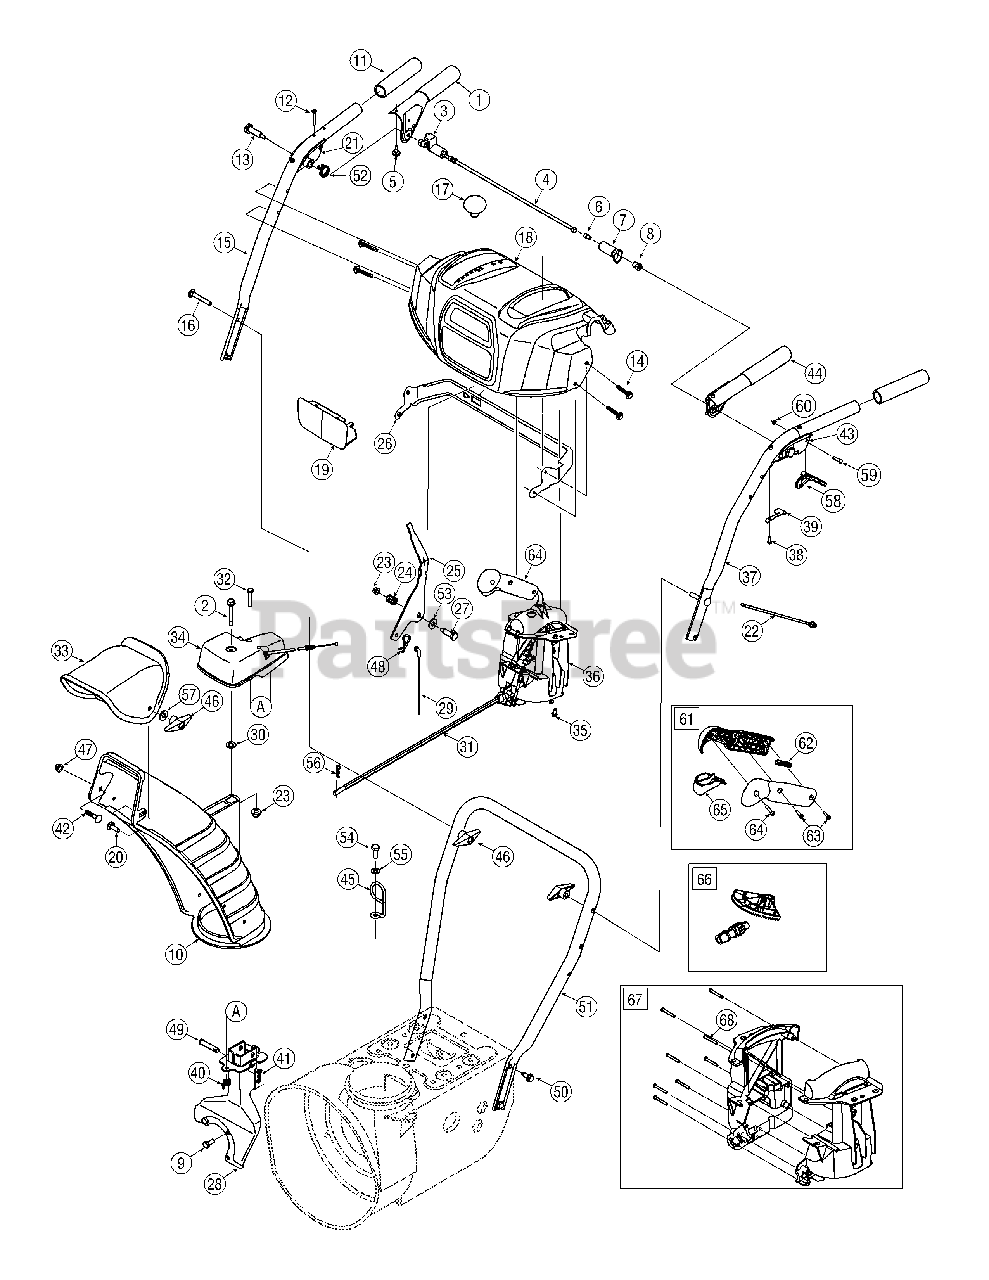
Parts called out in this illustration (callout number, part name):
1	Handle Engagement Assembly RH
2	Flange Shoulder Screw
3	Lock Plate
4	Pivot Rod
5	Rubber Bumper
6	Screw, 1/4-20 x .500
7	Clutch Lock Cam
8	Shoulder Nut, 1/4-20
9	Hex Screw, 5/16-24 x .750
10	Lower Chute
11	Handle Grip
12	Screw, #10-24 x 0.375
13	Shoulder Screw, 1/4-20
14	Screw, 1/4-20 x 1.625
15	Upper Handle RH
16	Carriage Screw, 5/16-18 x 2.25
17	Shift Knob
18	Handle Panel
20	Carriage Bolt, 5/16-18 x 1.0
21	Handle Clutch Lock RH Assembly
22	Cable Tie
23	Flange Lock Nut, 1/4-20
24	Compression Spring
25	Shift Lever
26	Panel Bracket
27	Shoulder Screw
28	Chute Support Bracket
29	Speed Selector Cable
30	Flat Washer, .25 x .630 x .0515
31	Chute Rod
32	Hex Screw, 1/4-20 x 3.00
33	Upper Chute
34	Gearbox Assembly
35	Hi-Lo Screw, 1/4-15 x 0.5
36	2-Way Chute Control Assembly
37	Upper Handle LH
38	Screw, #8-16 x 0.50
39	Clutch Lock Spring
40	Wing Nut, 1/4-20
41	Bow Tie Cotter Pin
42	Carriage Bolt, 5/16-18 x .750
43	Handle Clutch Lock LH Assembly
44	Handle Engagement Assembly
45	Cable Control Wire
46	Wing Knob
47	Flange Lock Nut, 5/16-18
48	Click Pin
49	Clevis Pin
50	Screw, 5/16-18 x 0.75
51	Lower Handle
52	Torsion Spring
53	Flat Washer
54	Screw, M8-1.25
55	Flat Washer, .330 x .630 x .0635
56	Cotter Pin
57	Flat Washer, .349 x .879 x .063
58	Steering Control
59	Pin, 3/16
60	E-Ring
61	Handle Assembly
62	Handle Plunger
63	Screw, Mach., #8-32 x .750
64	Screw, #8 x 1.00
65	Handle Lever
66	Gear Set Assembly
67	Handle Housing Assembly
68	Screw, #8-18 x 1.250
